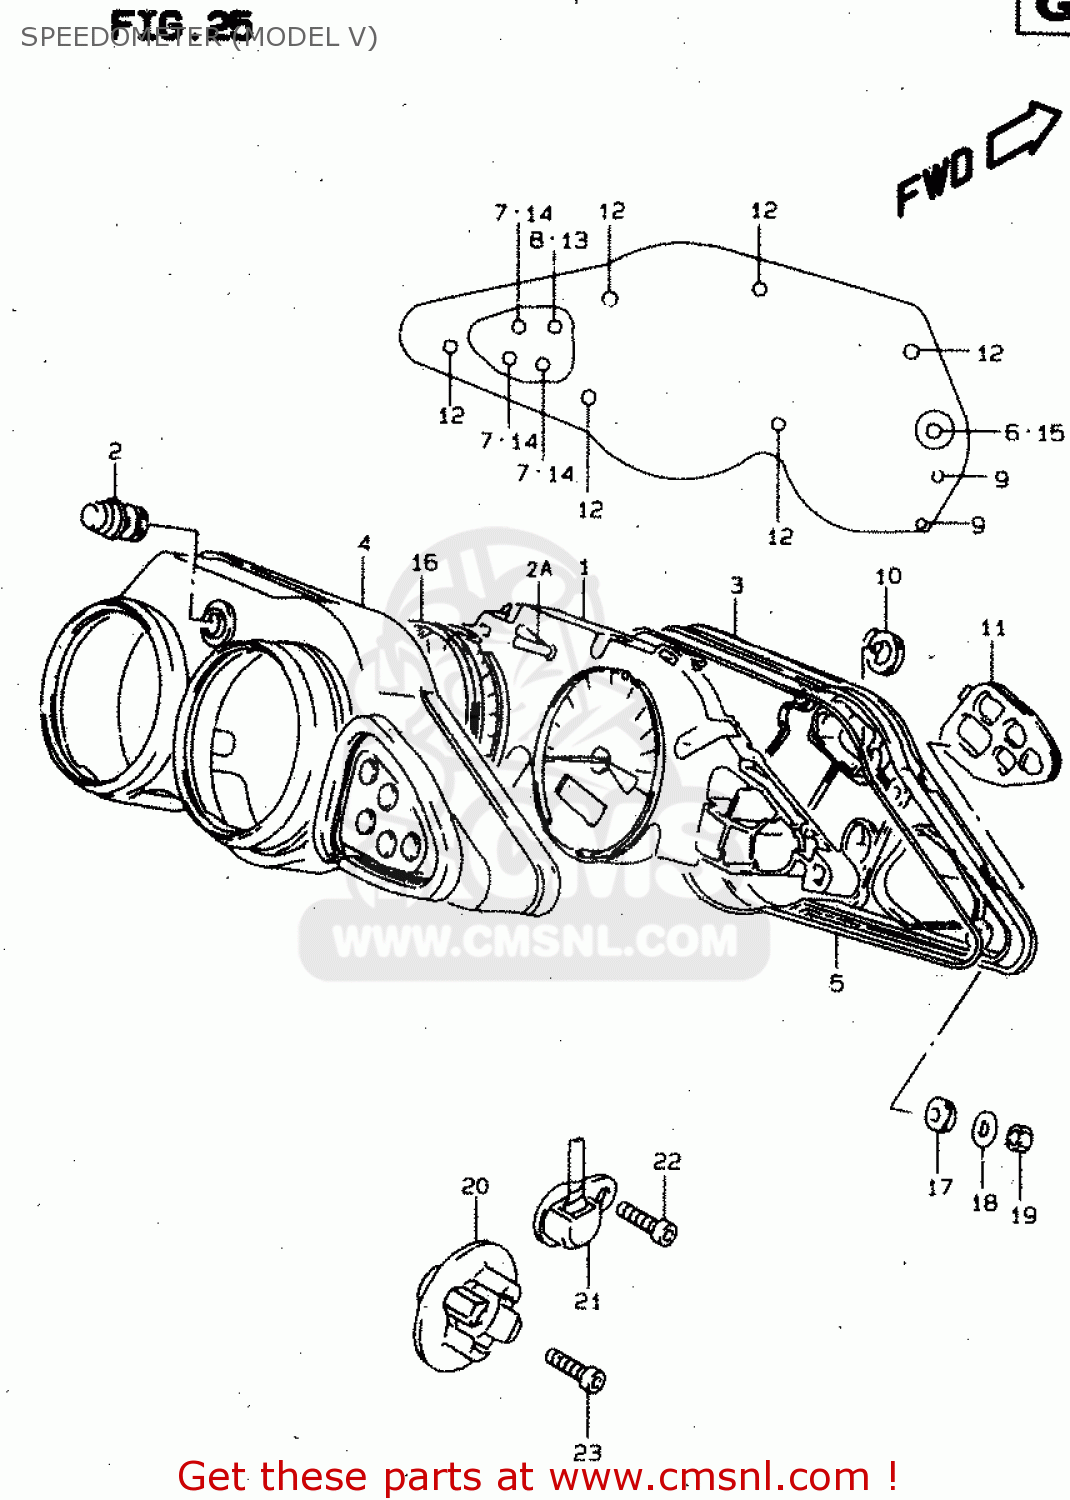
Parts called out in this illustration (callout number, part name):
1	SPEEDOMETER(KILO)
2	SWITCH,GUM
2A	LEVER
3	CASE ASSEMBLY
4	VISOR
5	GASKET (NAS)
6	SOCKET,BULB
7	SOCKET
8	SOCKET
9	SCREW(4X14)
10	BLIND,CAP
11	BLIND
12	SCREW
13	BULB(12V3W,WB371,T7)
14	BULB(12V1.7W,WB372,T7)
15	BULB(14V,0.84W)
16	CUSHION
17	CUSHION,METER
18	WASHER(5.5X16X1.2)
19	NUT
20	ROTOR,SPEED
21	SENSOR,SPEED
22	BOLT
23	BOLT
